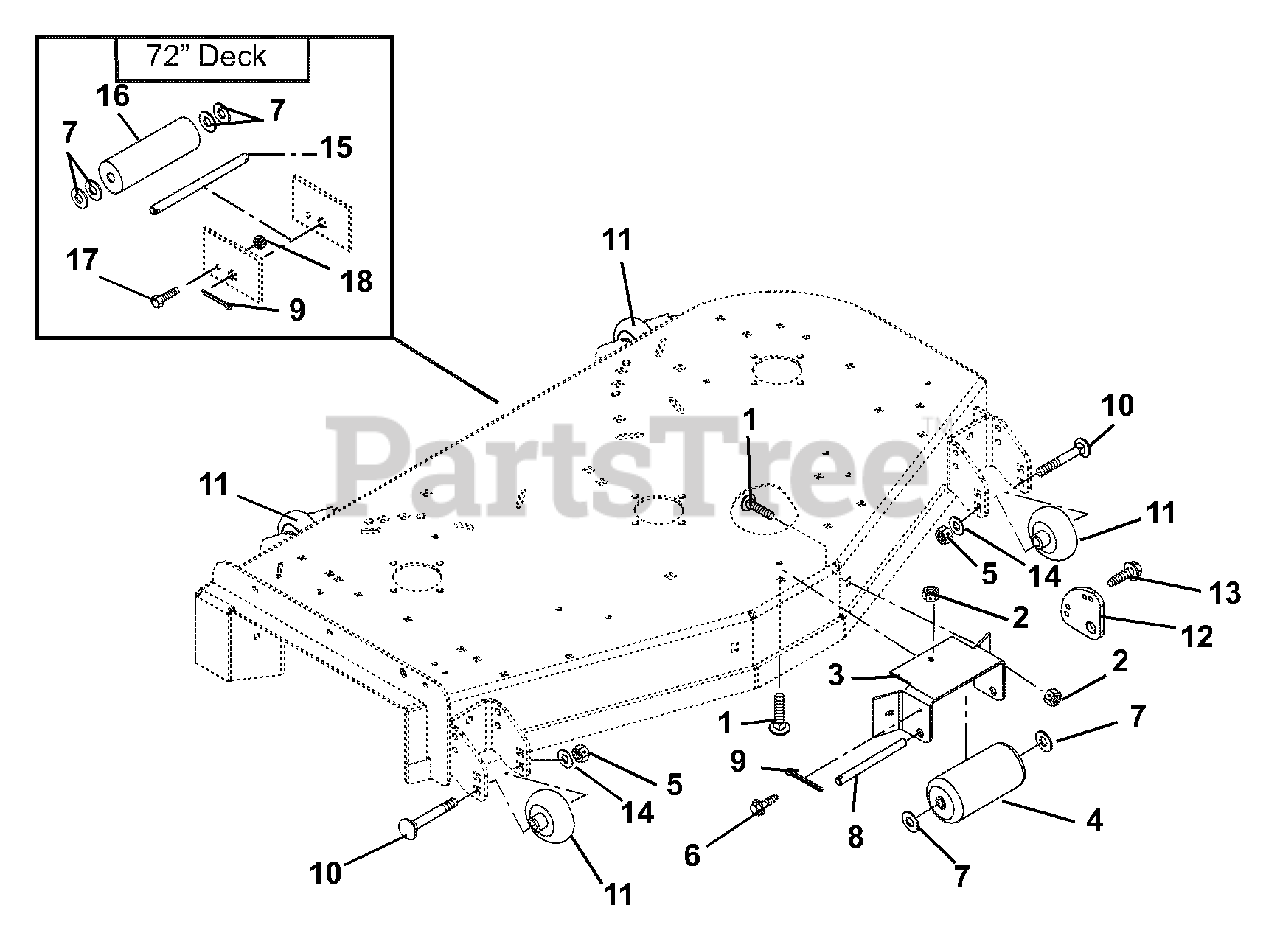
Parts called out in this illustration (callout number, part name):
1	Bolt-Round Head Square Neck .38-16 x 1.00 Grade 5
2	Nut-Locking-Top-Flange .38-16
3	Bracket- Anti-Scalp Roller
5	Nut-Locking-Nylon .50-13
6	Screw-Tapping .25-20 x .75 Hex Washer Head
7	Washer-Flat-Steel .656 x 1.31 x .095 (058, 060, 073, 075, 318, 319)
7	Washer-Flat-Steel .656 x 1.31 x .095 (059, 061, 074, 076)
9	Pin-Cotter .25 x 2.00 (058, 060, 073, 075, 318, 319)
9	Pin-Cotter .25 x 2.00 (059, 061, 074, 076)
10	Bolt-Round Head Square Neck .50-13 x 5.00 Grade 2
11	Wheel, 3 x 5
12	Anti-Scalp Washer
13	Screw-Tapping .25-20 x .62 Hex Washer Head
14	Washer-Flat-Steel .531 x 1.06 x .095
15	Shaft, Center Roller (059, 061, 074, 076)
16	Roller, Gage (059, 061, 074, 076)
17	Bolt-Hex .25-20 x .75 Grade 5 (059, 061, 074, 076)
18	Nut-Locking-Center .25-20 (059, 061, 074, 076)
